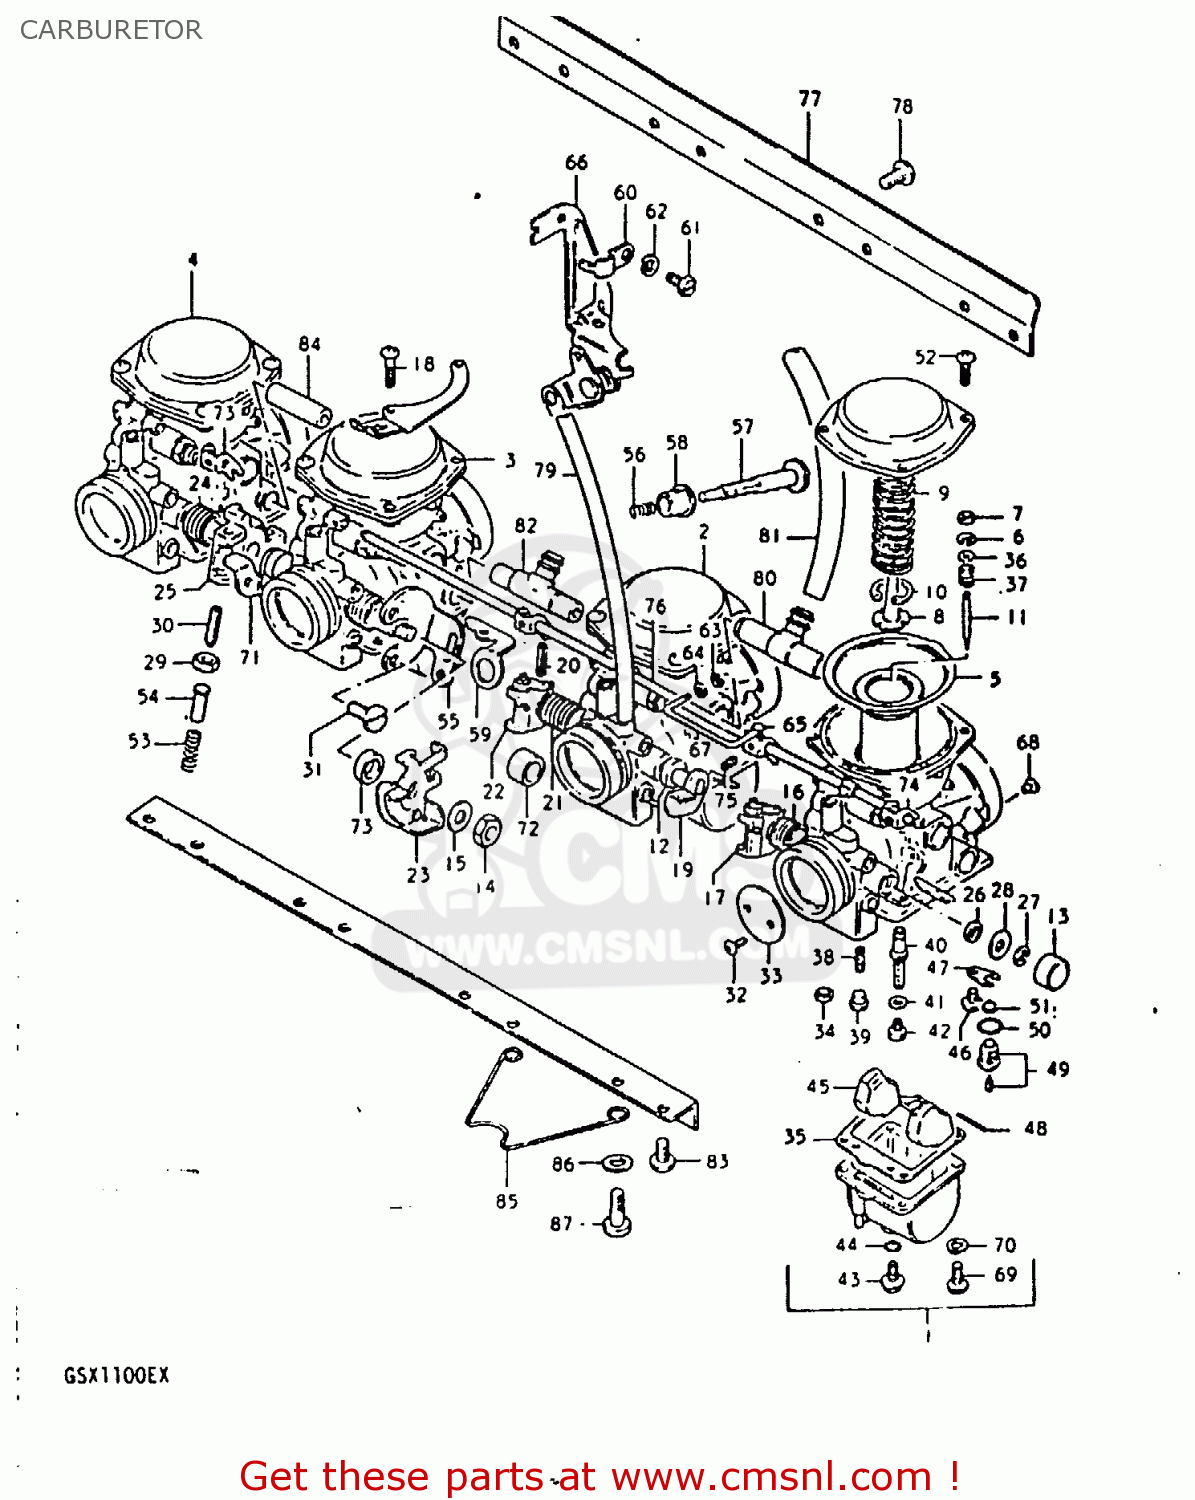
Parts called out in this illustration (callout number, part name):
1	CARBURETOR, NO.1
2	CARBURETOR, NO.2
3	CARBURETOR, NO.3
4	CARBURETOR NO.4
5	DIAPHRAGM
6	CLIP,NEEDLE
7	RING
8	HOLDER,GUIDE
9	SPRING
10	E RING
11	NEEDLE,JET
12	GASKET
13	CAP
14	NUT
15	WASHER
16	SPRING,THROTTLE SHAFT
17	SHAFT,THROTTLE
18	SCREW
19	SHAFT,THROTTLE
20	PIN,THROTTLE SHAFT
21	SPRING,THROTTLE SHAFT
22	LEVER,THROTTLE SHAFT
23	LEVER ASSEMBLY,THROTTLE
24	SPRING,THROTTLE SHAFT
25	SHAFT,THROTTLE
26	SEAL
27	E RING
28	GASKET,THROTTLE SHAFT (NAS)
29	NUT
30	SCREW
31	SCREW
32	SCREW
33	VALVE,THROTTLE (BUTTERFLY)
34	GASKET (NAS)
35	GASKET,FLOAT CHAMBER (NAS)
36	WASHER
37	SPRING
38	JET
39	PLUG,NEEDLE JET
40	JET, NEEDLE (X-1)
41	WASHER,NEEDLE NOZZLE
42	JET
43	PLUG,DRAIN
44	GASKET (NAS)
45	FLOAT
46	SCREW
47	PLATE
48	PIN,FLOAT
49	VALVE ASSEMBLY,NEEDLE
50	O-RING,NEEDLE VALVE
51	FILTER
52	SCREW
53	SPRING,THROTTLE SCREW
54	PIN,THROTTLE LEVER
55	BRACKET,THROTTLE ADJUST
56	SPRING
57	SCREW
58	BUSH
59	BRACKET,THROTTLE ADJUST
60	BRACKET,STARTER
61	BOLT
62	LOCK WASHER
63	CAP,LEVER
64	SEAT,SPRING
65	LEVER ASSY
66	BRACKET
67	ROD,STARTER LEVER
68	JET,AIR(140)
69	SCREW
70	LOCK WASHER
71	SHAFT,THROTTLE
72	RING
73	RING
74	LEVER
75	SCREW
76	SHAFT,STARTER
77	BRACKET
78	SCREW
79	HOSE
80	NIPPLE
81	HOSE
82	NIPPLE
83	SCREW 6X12
84	NIPPLE
85	CLAMP
86	WASHER
87	SCREW
